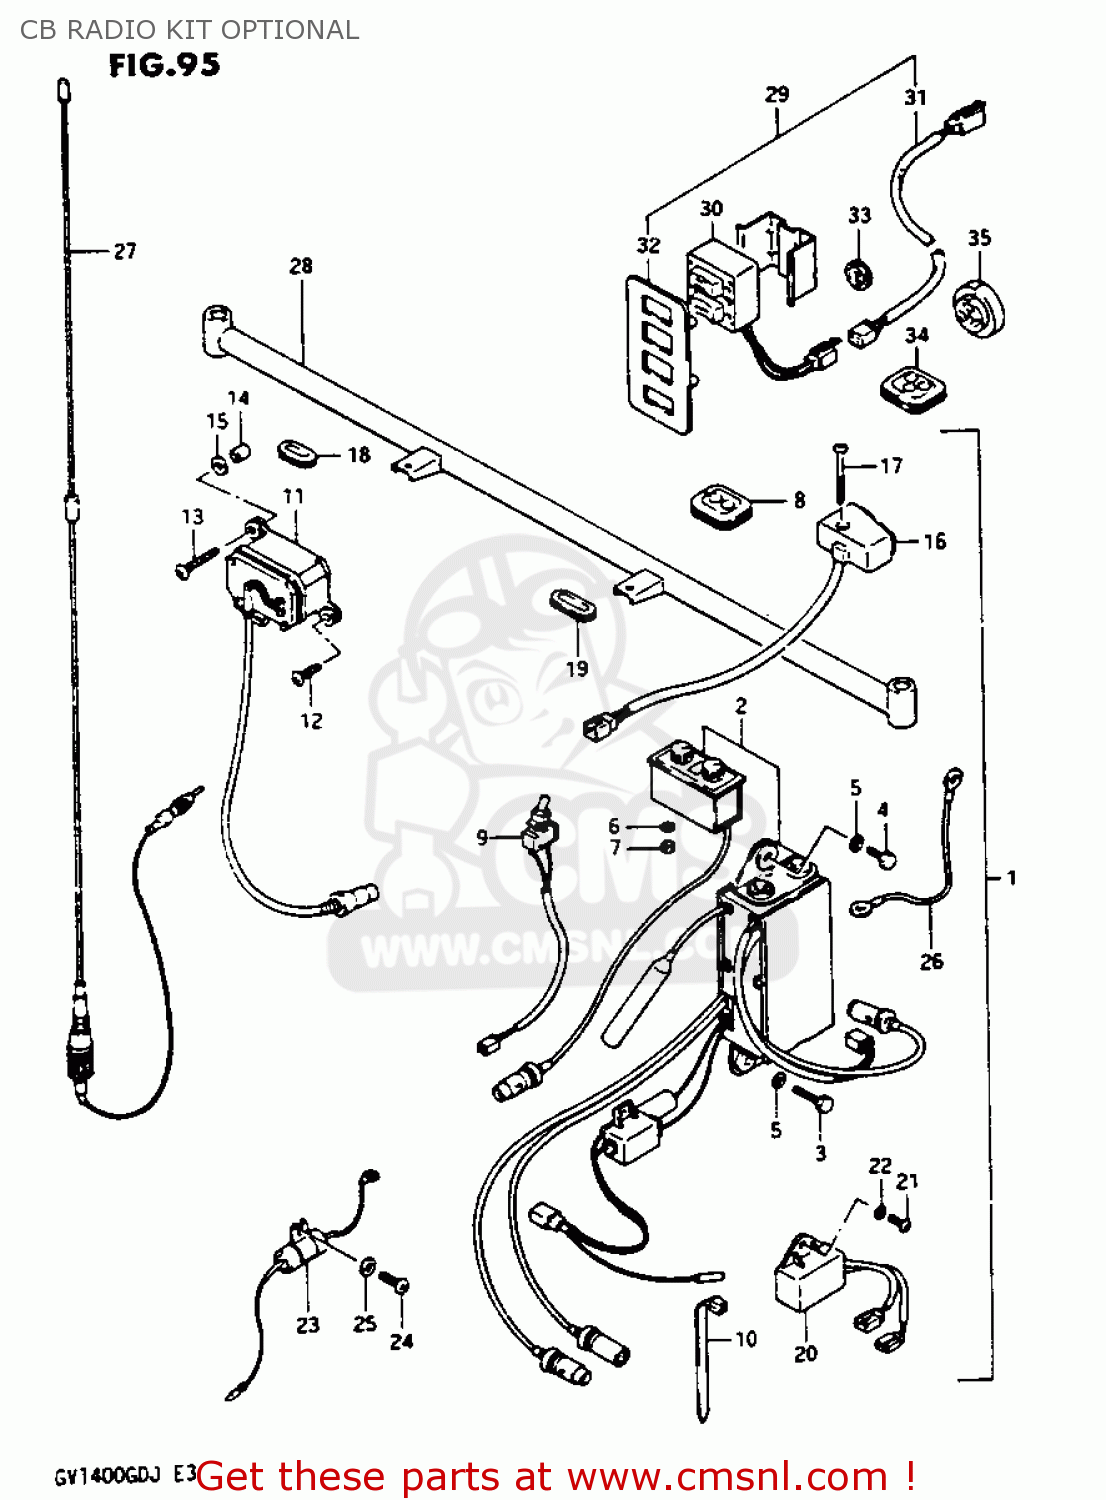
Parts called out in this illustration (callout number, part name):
1	RADIO SET,CB
2	CB TRANSCEIVER SET
3	BOLT
4	BOLT
5	LOCK WASHER
6	LOCK WASHER
7	NUT M4 DIN 985
8	GROMMET
9	SWITCH ASSEMBLY,CB BACK UP
10	CLAMP(L:165)
11	INDICATOR ASSEMBLY,CB CHANNEL
12	SCREW
13	SCREW
14	SPACER (5.2X8X12.5)
15	WASHER (4X16X1.2)
16	SWITCH ASSEMBLY,CB CHANNEL SELECT
17	SWITCH
18	GROMMET
19	GROMMET
20	FILTER,FAN MOTOR NOISE
21	SCREW
22	WASHER
23	CONDENSER,CB UNIT
24	SCREW
25	WASHER
26	WIRE
27	ANTENNA ASSY,CB TRANSCIVER
28	HOLDER,ANTENNA BAR
29	CB CO-RIDER REMOTE CONTROL SWITCH
30	SWITCH
31	WIRE,CB SELECT SWITCH
32	PANEL,TUNER ASSEMBLY NO
33	GROMMET, WIRE
34	GROMMET WIRE
35	GROMMET WIRE
